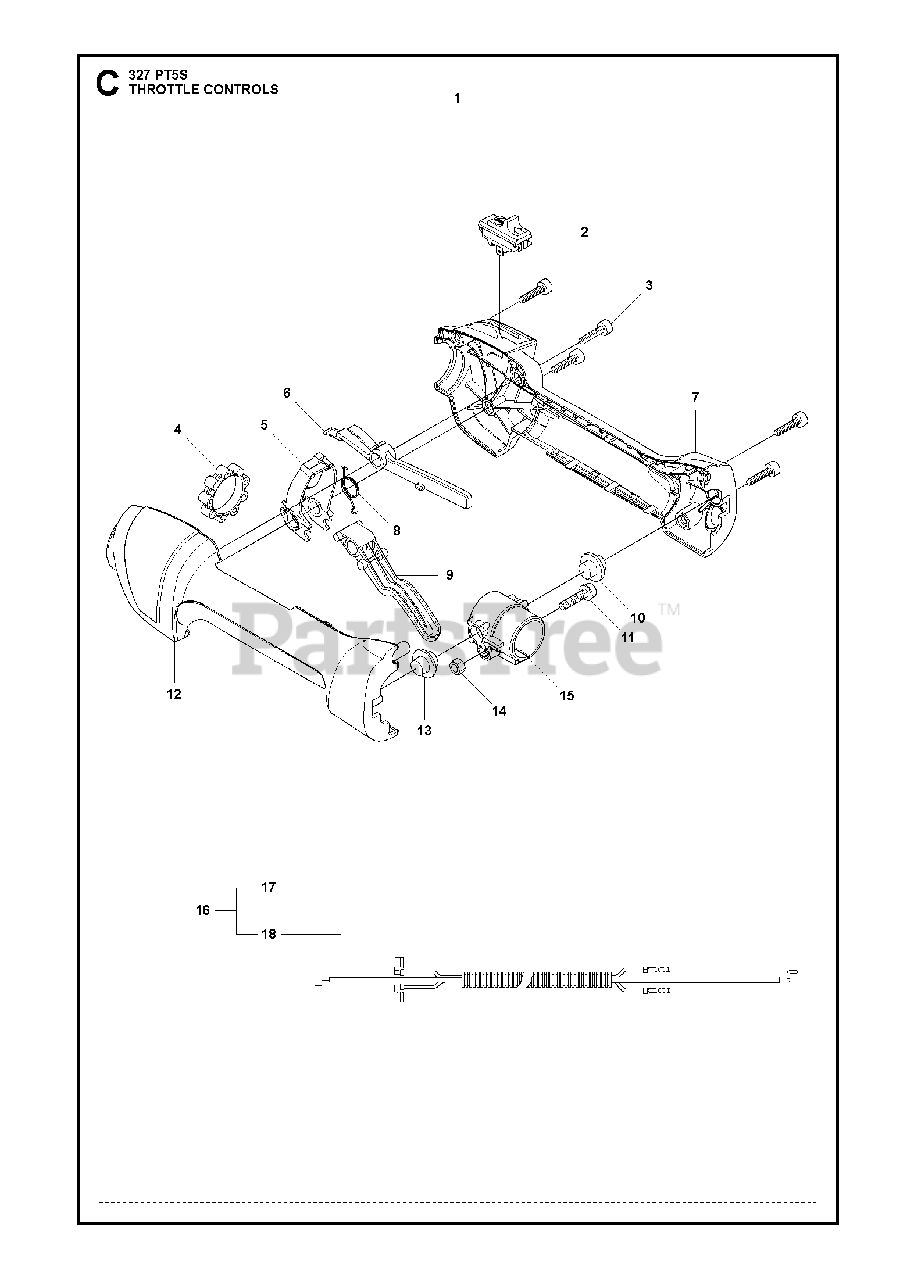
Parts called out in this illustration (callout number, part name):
2	STOP BUTTON
3	SCREW
4	VIBRATION DAMPER
6	THROTTLE LOCK
7	HANDLE
8	RETURN SPRING
9	THROTTLE TRIGGER
10	VIBRATION ABSORBER
12	HANDLE
13	VIBRATION ABSORBER
14	NUT
15	HOLDER
16	WIRING
17	SHORT CIRCUIT CABLE
18	THROTTLE WIRE ASSY
